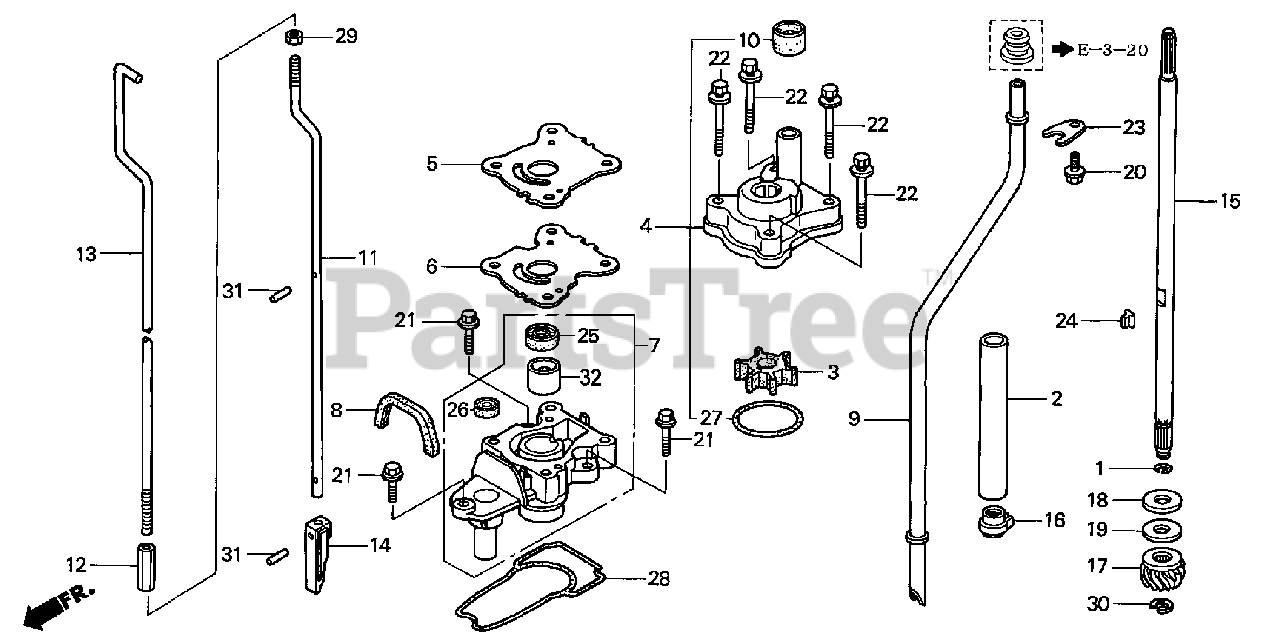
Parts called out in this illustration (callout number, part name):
1	CLIP, VALVE GUIDE
2	GUIDE, OIL (S,L)
3	IMPELLER, PUMP (S,L)
4	HOUSING ASSY., IMPELLER
5	COVER, IMPELLER
6	GASKET, IMPELLER
7	HOUSING, WATER PUMP (S,L)
8	GROMMET, WATER PUMP HOUSING
9	TUBE, WATER (S)
10	RING, WATER TUBE SEAL
11	ROD B, SHIFT (S)
12	JOINT, SHIFT ROD
13	ROD A, SHIFT (S)
14	ROD, PUSH
15	SHAFT, VERTICAL (S)
16	SLINGER, OIL (S,L)
17	GEAR, PINION
18	WASHER A, THRUST BEARING
19	WASHER B, THRUST BEARING
19	WASHER C, THRUST BEARING
20	BOLT, FLANGE (6X12)
21	BOLT, FLANGE (6X20)
22	BOLT-WASHER (6X50)
23	PLATE, WATER TUBE SETTING
24	KEY, WOODRUFF
25	SEAL, WATER (13MM) (ARAI)
26	SEAL, WATER (6MM)
27	O-RING (42.2X2.4)
28	O-RING, WATER PUMP HOUSING
29	NUT, HEX. (6MM)
30	E-RING (8MM)
31	ROLLER (2.5X11.8)
32	BUSH (13X15X15)
